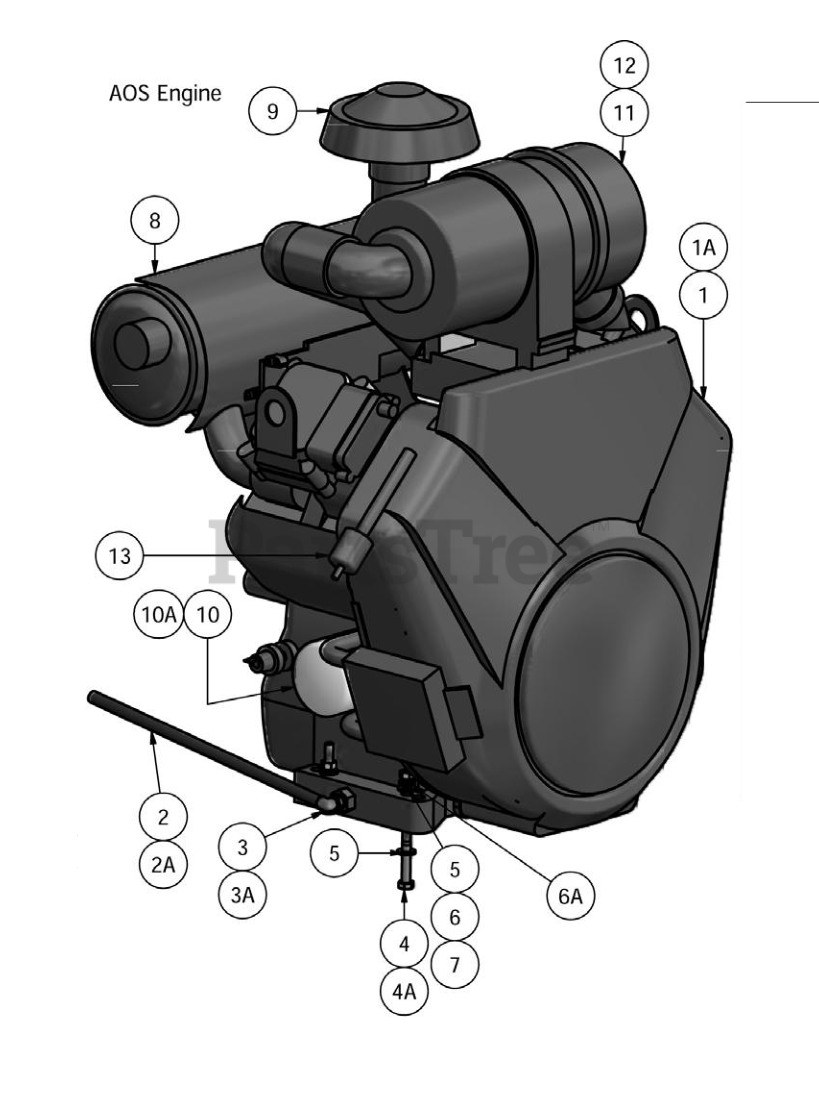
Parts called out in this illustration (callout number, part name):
1	35hp Briggs Vanguard
1A	27hp Kawasaki Engine with Donaldson Air Filter
2	Oil Drain Hose (35hp Only)
2A	Oil Drain Hose (27hp Only)
3	Oil Drain Fitting (35hp Only)
3A	Oil Drain Fitting (27hp Only)
4	5/16" x 2 1/2" Bolt (35hp Only)
4A	10mm x 552 Bolt (27hp Only)
5	5/16" Flat Washer
6	5/16" Lock Washer (35hp Only)
6A	7/16" Lock Washer (27hp Only)
8	35hp Vanguard Muffler
9	Mushroom Cap
10	Oil Filter (35hp Only)
10A	Oil Filter (27hp Only)
11	Air Filter (Outer)
12	Air Filter (Inner)
13	Briggs Fuel Filter
13A	Kawasaki Fuel Filter
